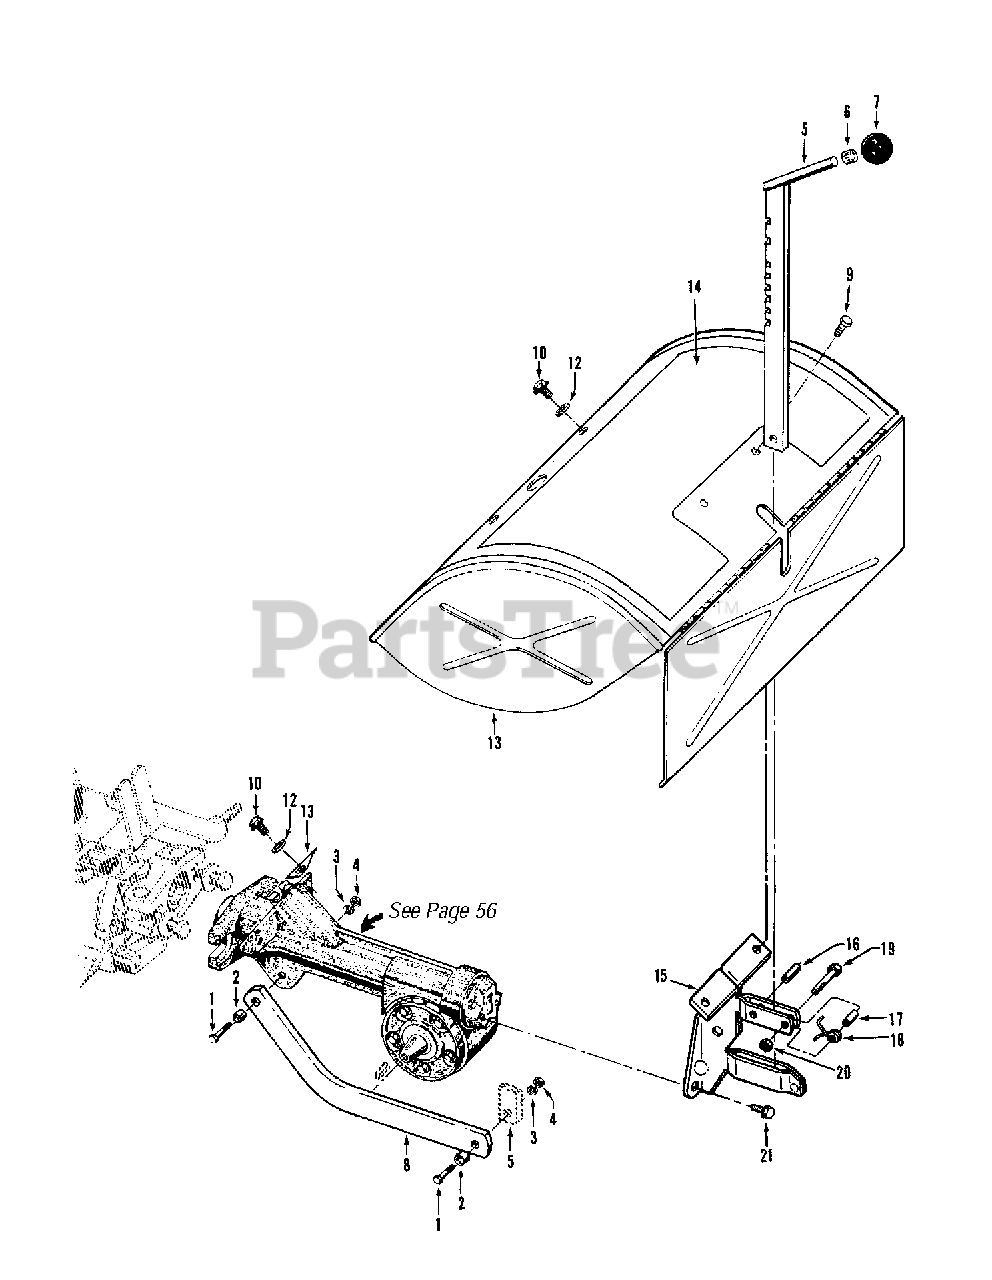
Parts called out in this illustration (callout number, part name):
1	Bolt-hex hd., 3/8-16 x 1-1/4"
2	Bushing-19/64" (.300" lg.)
3	Lockwasher-spring lock, 3/8"
4	Nut-hex, 3/8"-16
5	Bar-depth regulator
6	Ring-retaining
7	Knob-depth regulator
8	Bar-drag, depth regulator
9	Screw-thread-forming, 1/4-20 x 1/2"
10	Bolt-flanged hex hd., 5/16-18 x 3/4"
12	Washer-flat, 5/16"
13	Hood
14	Decal-hood, operating instructions
15	Bracket
16	Pin-roll (spirol) 1/4" x 1"
17	Spacer
18	Spring
19	Bolt-hex hd., 1/4-20x1"
20	Locknut-1/4"-20
21	Bolt-flanged hex hd., 5/16-18 x 5/8"
